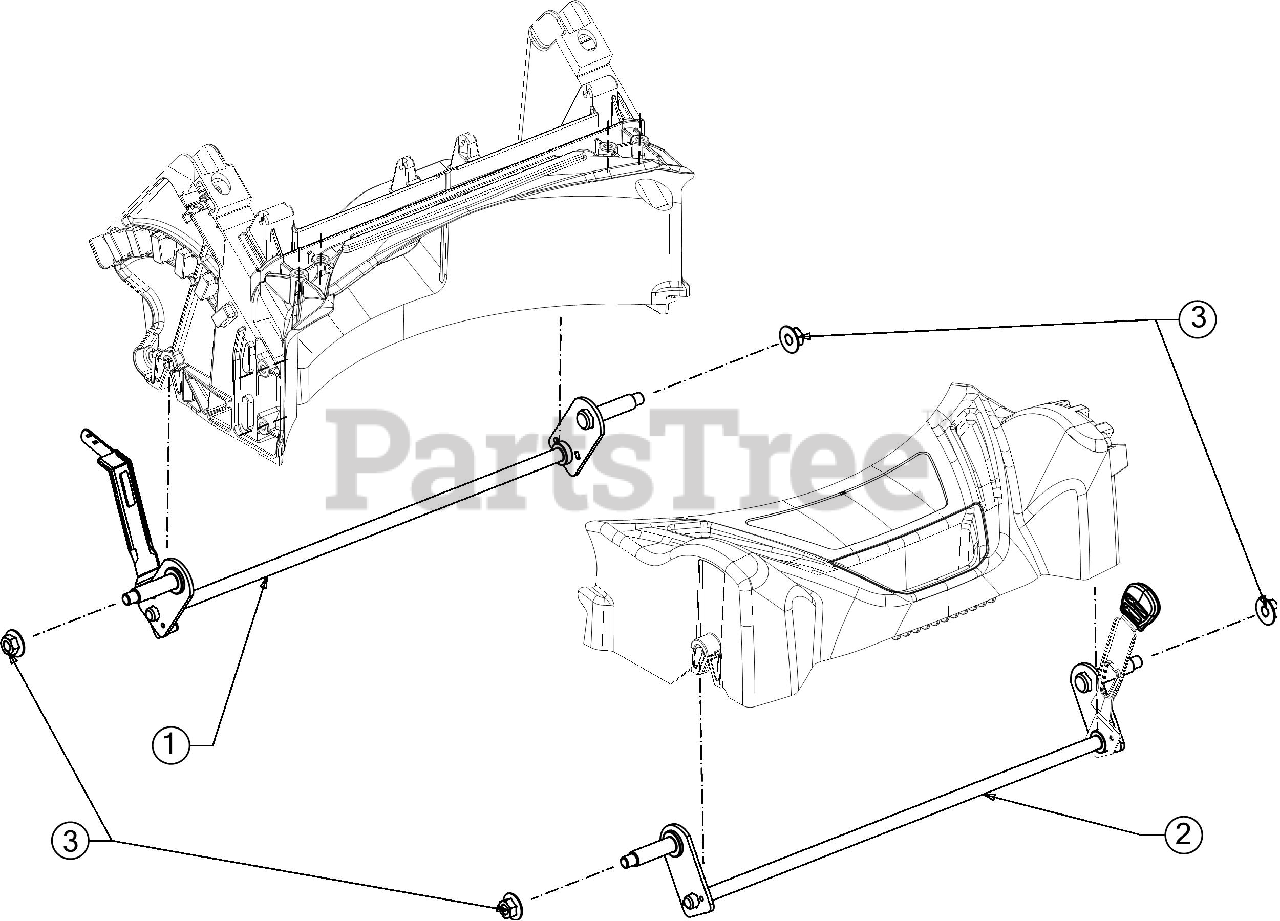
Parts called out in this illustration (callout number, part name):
1	8" REAR AXLE ASSEMBLY
2	FRONT AXLE ASSEMBLY
3	FLANGE LOCK NUT
